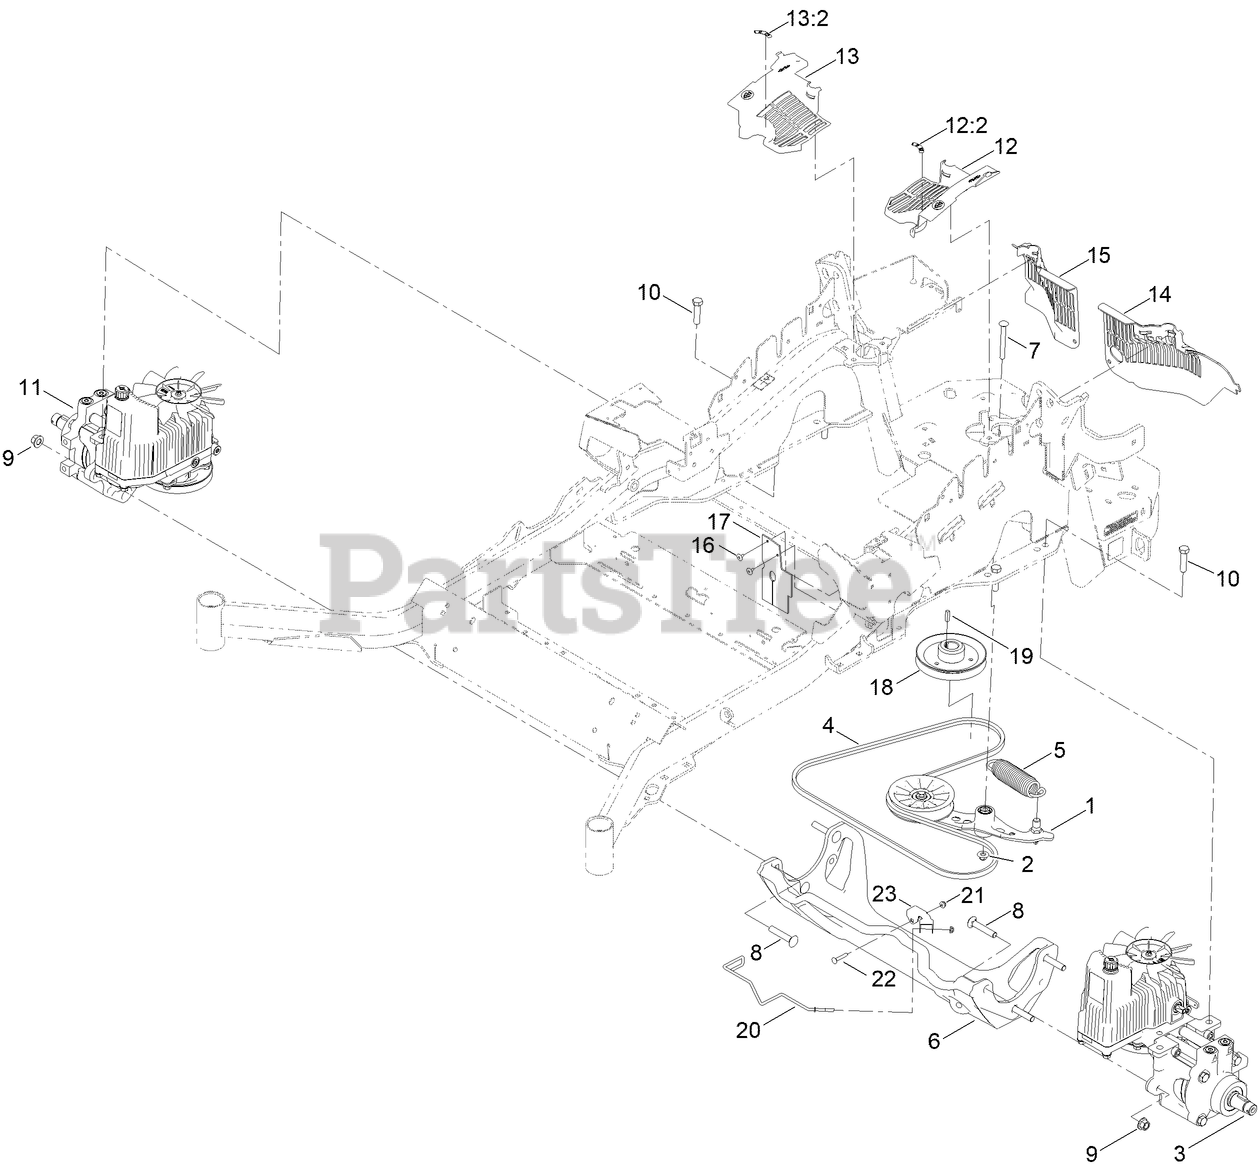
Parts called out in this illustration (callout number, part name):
1	PUMP IDLER ASM
2	NUT-FLANGE, NI
3	HYDRO-LH
4	BELT-V
5	SPRING-EXTENSION
6	CRADLE-HYDRO
7	BOLT-SHOULDER, CARRIAGE
8	SCREW-CARR
9	NUT-LOCK
10	SCREW-HH
11	HYDRO-RH
12	LH HYDRO GUARD ASM
12:2	DECAL-OIL, HYDRO
13	RH HYDRO GUARD ASM
13:2	DECAL-OIL, HYDRO
14	GUARD-HYDRO, REAR (LH)
15	GUARD-HYDRO, REAR (RH)
16	RIVET-POP
17	DEFLECTOR-AIR FLOW
18	SHEAVE, W/HUB
20	GUIDE-BELT
21	NUT-HF
22	SCREW-CARR
23	BRACKET-U
